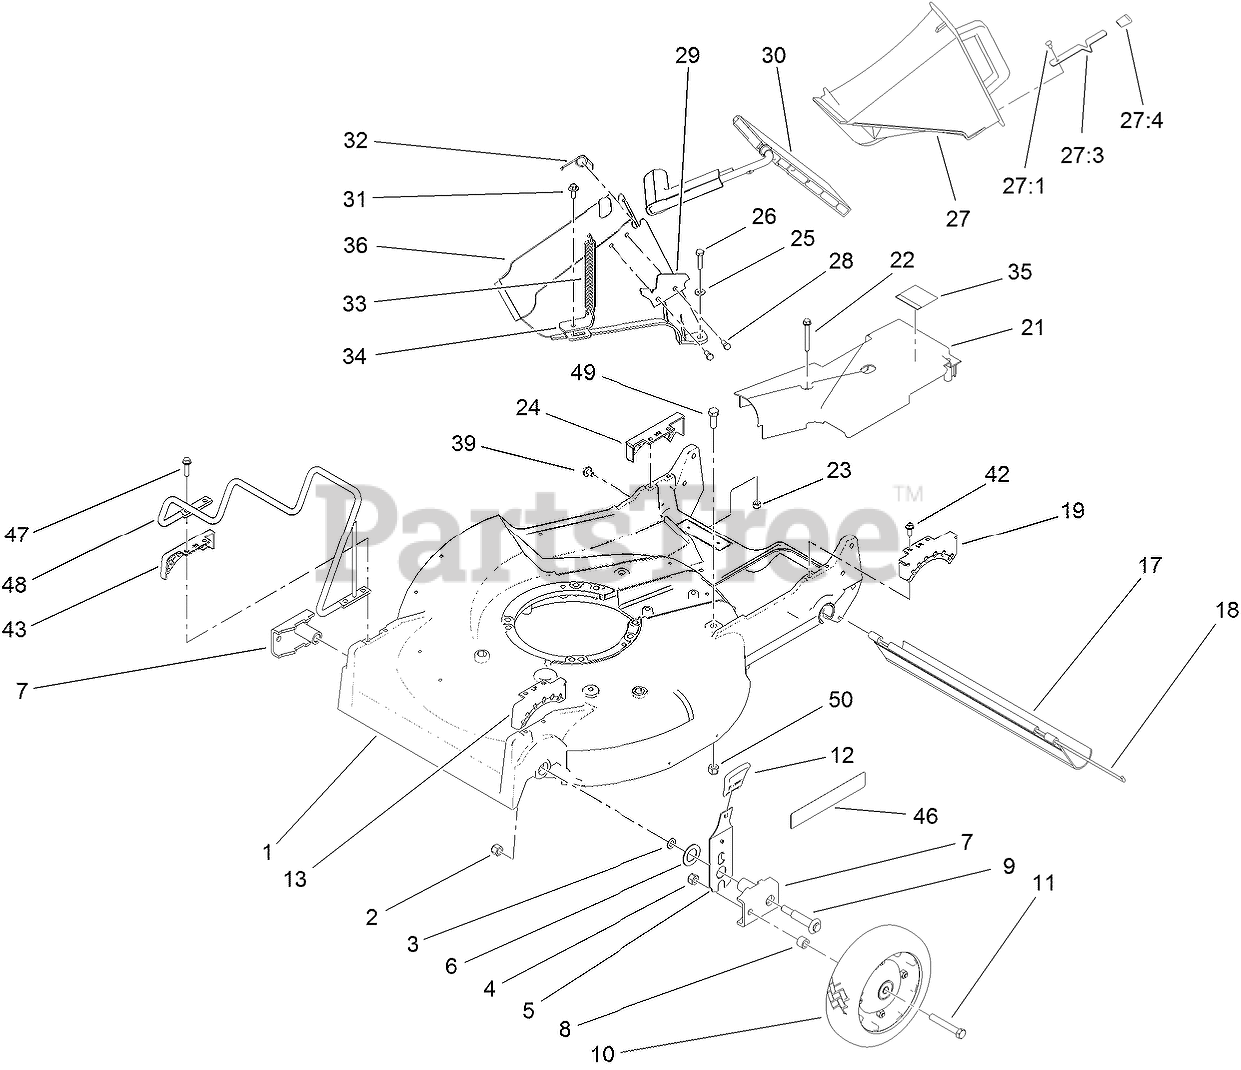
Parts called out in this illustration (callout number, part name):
1	HOUSING
2	NUT-LOCK
3	WASHER
4	NUT-LOCK, CONE
5	FRONT SPRING ARM ASM
6	WASHER-THRUST
7	ARM-PIVOT, FRONT
8	SPACER-WHEEL
9	SCREW-SHOULDER
10	WHEEL AND TIRE ASM
11	SCREW-HH
12	KNOB-HOC
13	QUADRANT-FRONT, LH
17	SHIELD-TRAILING
18	ROD-SHIELD
19	QUADRANT-REAR, LH
21	COVER-BELT
22	SCREW-HWHTF
23	NUT-LOCK, NI
24	QUADRANT-REAR, RH
25	WASHER-FLAT
26	SCREW-HH
27	DISCHARGE PLUG ASM
27:1	RIVET-HEAD, FLAT
27:3	LATCH-PLUG, DISCHARGE
27:4	GRIP-LATCH
28	SCREW-PLASTITE
29	LATCH-PLATE
30	DISCHARGE DOOR ASM
31	SCREW-HWH
32	RETAINER-DOOR
33	SPRING-DOOR
34	BRACKET-SPRING
35	DECAL-GREASE
36	TUNNEL-DISCHARGE
39	SCREW AND WASHER ASM
42	SCREW-HWHTF
43	QUADRANT-FRONT, RH
47	SCREW-HWHTF
48	GUARD-ENGINE
49	SCREW-HH
50	NUT-LOCK, NI
